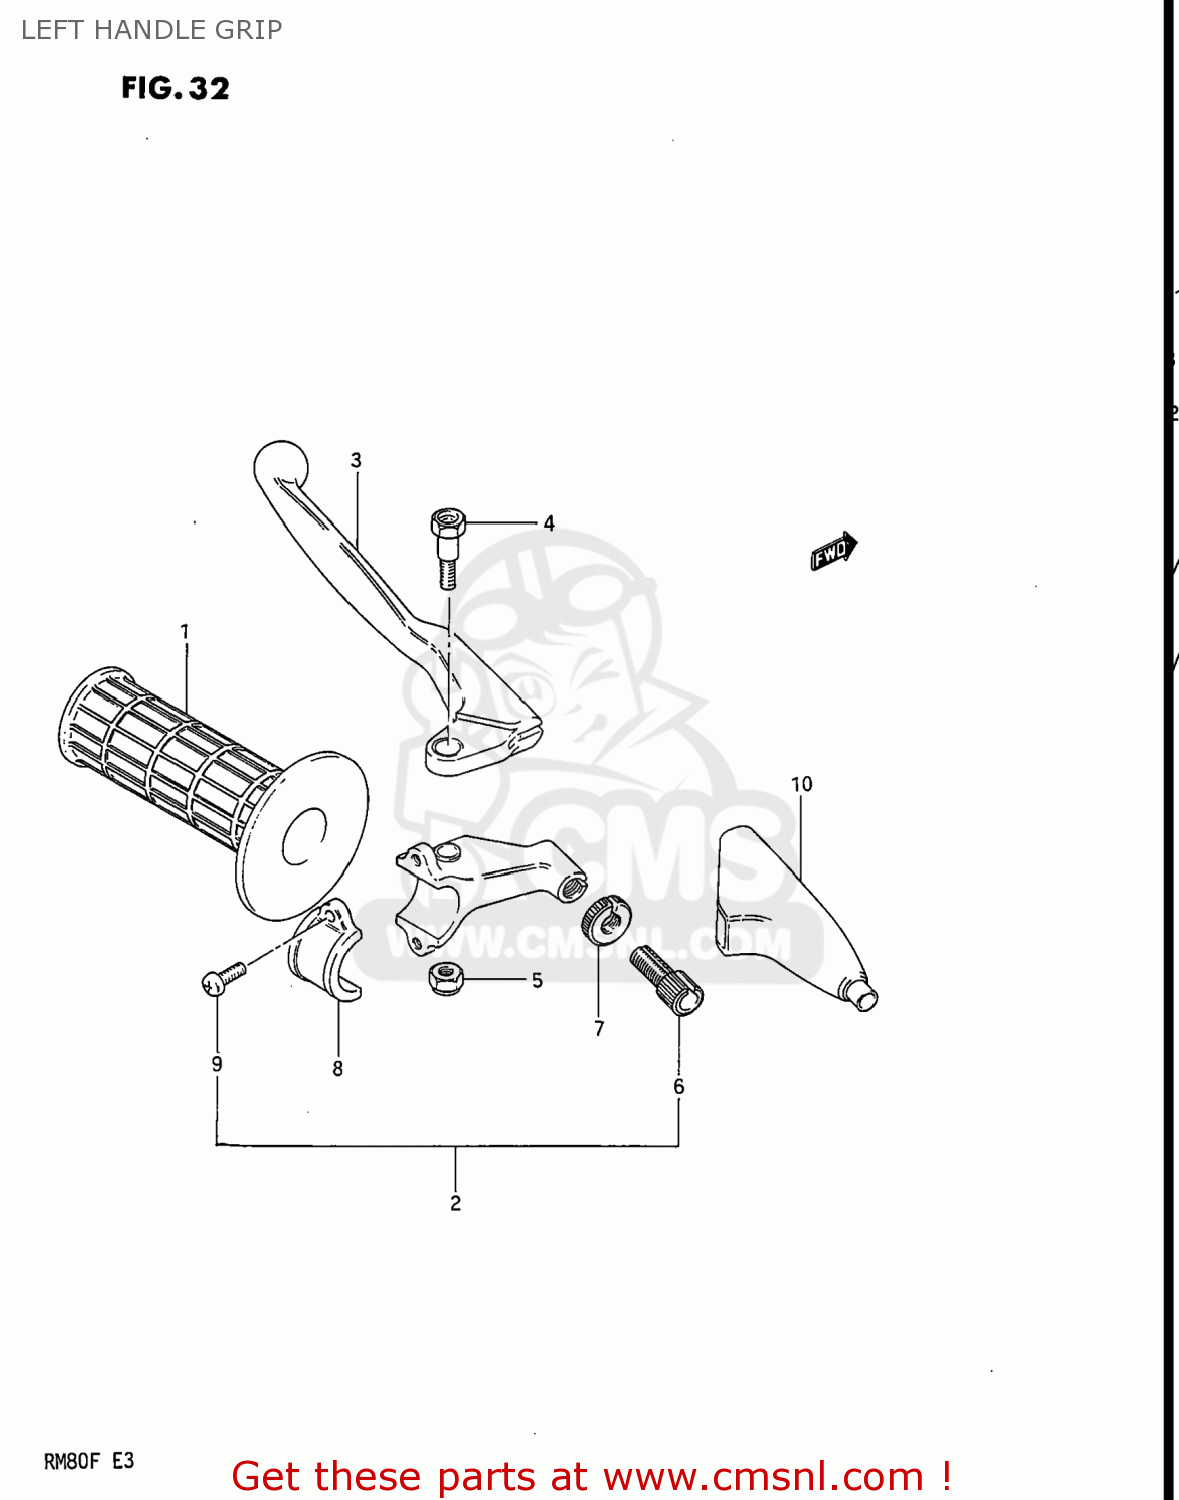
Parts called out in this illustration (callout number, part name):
1	GRIP,LEFT
2	LEVER ASSY,CLUTCH
3	LEVER,CLUTCH
4	BOLT,LEVER
5	NUT 6MM
6	ADJUSTER,CABLE
7	NUT,CABLE ADJUSTER
8	BRACKET,CLUTCH LEVER HOLDER
9	SCREW
10	COVER,CLUTCH LEVER
